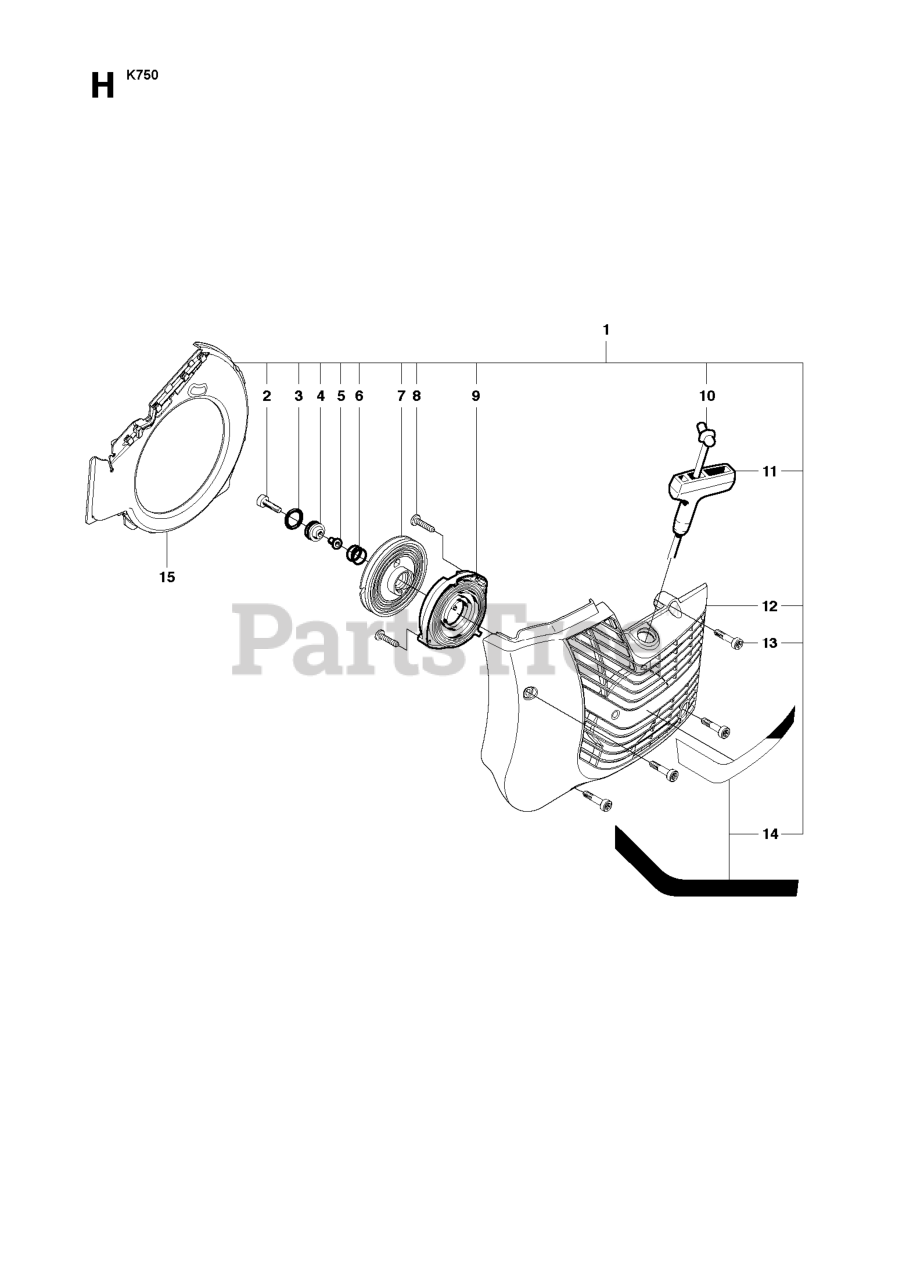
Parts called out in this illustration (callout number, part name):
1	RP STARTER ASSY K750
2	SCREW 1TXSCT
4	SEALING HOLDER
7	STARTER PULLEY
9	RETURN SPRING
10	STARTER ROPE 50 M
10	STARTER ROPE
11	STARTER HANDLE
12	STARTER COVER
15	AIR CONDUCTOR
